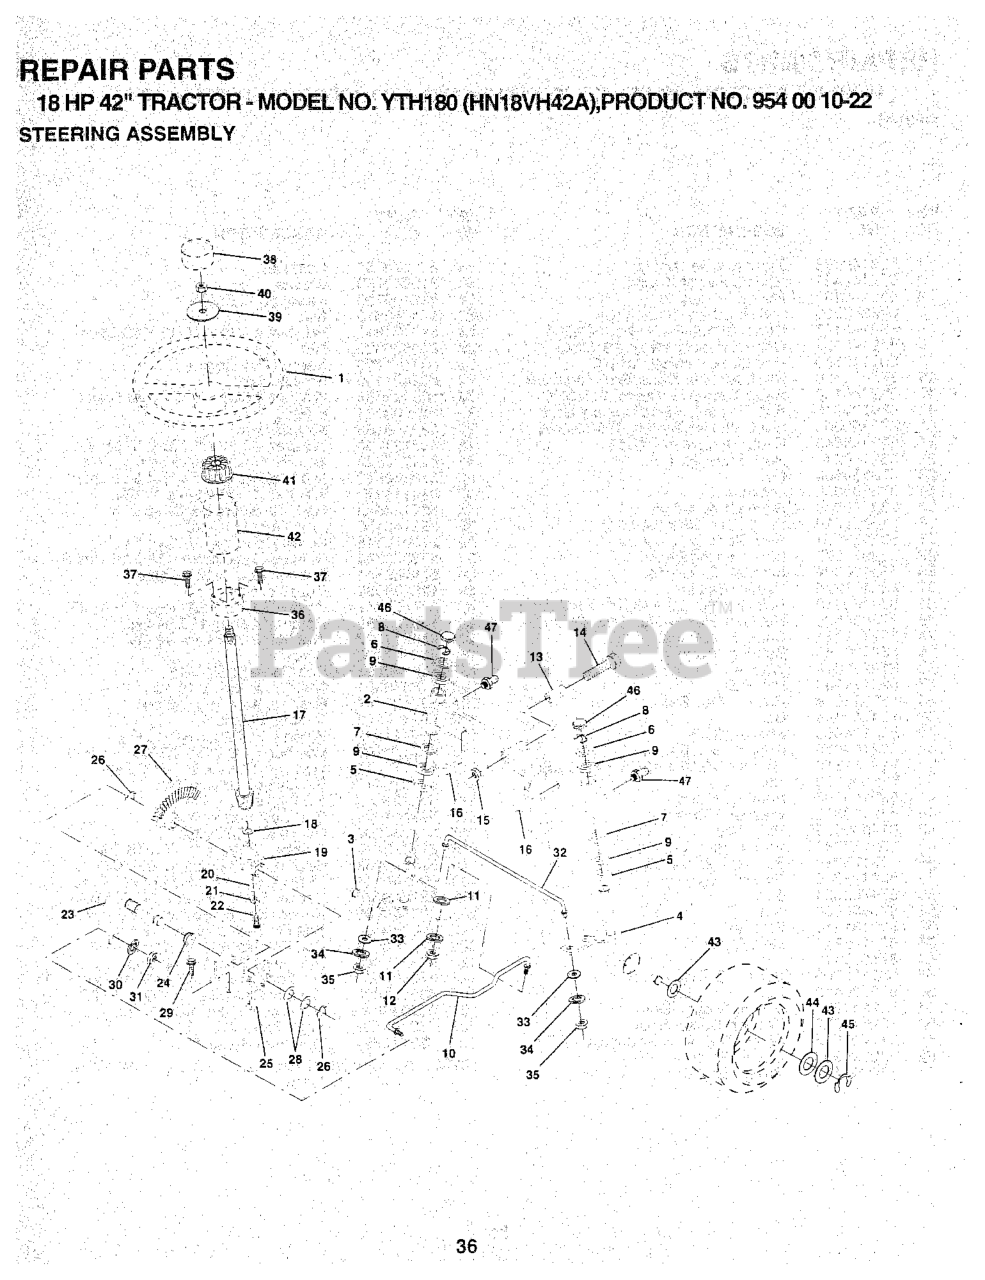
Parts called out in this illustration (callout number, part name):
1	STEERING WHEEL
3	SPINDLE LH
4	SPINDLE RH
5	THRUST WASHER
9	BRNG T
10	LINK.DRAG.SOL.BALL JT.20.064
11	WASHER, LOCK 3/8
12	NUT
13	BEARING
14	Bolt, Hex Head 5/8-11 x 3-1/2
15	NUT-LOC,FLANGE LT
17	SHAFT STR
18	THRUST WASHER
19	SHAFT,SUPPORT
20	WASHER
21	LOCKWASHER
22	SCREW,SPECIAL
23	SHAFT PITMAN
24	NYLINER T (7283A)
25	BRKT,STEERING
27	GEAR.SECTOR
28	THRUST WASHER
29	SCREW
30	WASHER, LOCK 3/8
31	NUT
32	TIE ROD
33	WASHER M
34	WASHER.LOCK.HVY.HLCL.SPR.5/16
35	LOCKNUT
36	BUSHING LT
37	SCREW LT
38	INSERT,STR WHEEL
40	NUT.HEX.1/2-20
41	ADAPTER LT
46	CAP.SPINDLE.BLACK
47	ZERK M
